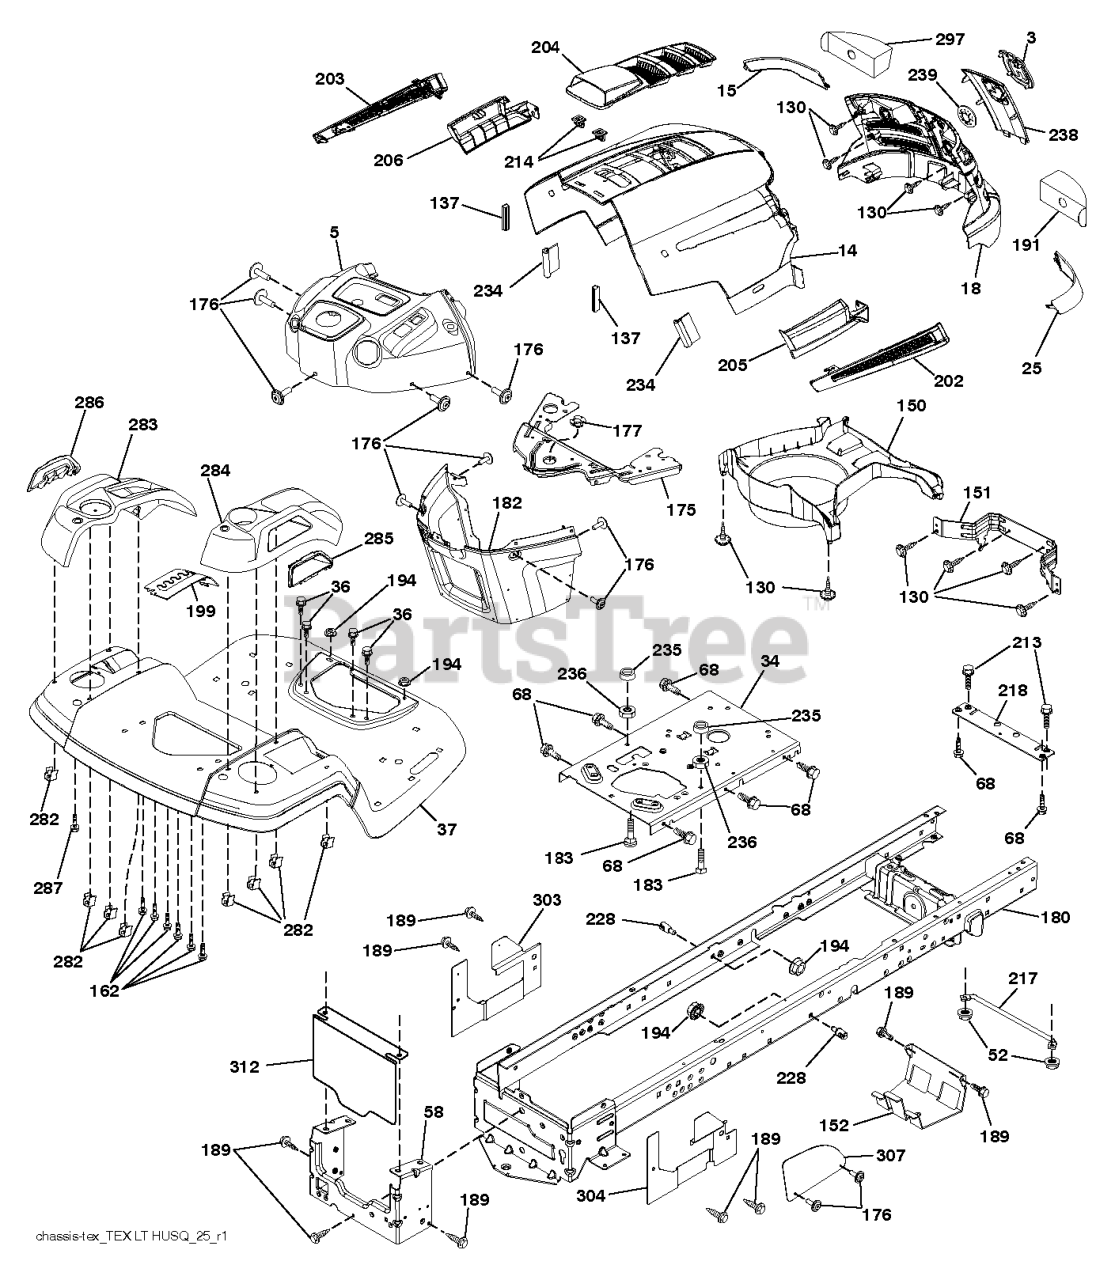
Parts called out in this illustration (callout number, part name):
1	DECK W/DECALS 42"
2	E-RING 1/2 (2 2)
5	BLADE OEM, 14-7/8
6	SPINDLE ASSY - 42/48"
7	SHAFT SEAL
9	SPLINED SHAFT - 42/48"
10	BOTTOM DUST CAP
11	TOP DUST CAP
12	PLUG-VENTED
13	HCS 5/16C X 1 1/4
14	HCS 5/8F X 1 1/4
15	LOCKWASHER 5/8
16	DISCHARGE CHUTE 42"
17	HCS 5/16C X 3/4
19	CARRIAGE BOLT 5/16C X 5/8"
20	CENTER BAFFLE
21	WASHER 5/16 FLAT
22	NUT 5/16 NYLOC
23	MAIN BAFFLE
24	STRUT WLDMT - RT
25	ZERK
26	HCS 5/8C X 2 GR.5
27	STRUT MOUNT WELDMENT
28	HCS 7/16C X 1 1/2
29	LIFT CHAIN
30	NUT 7/16C CENTERLOCK
31	NUT 7/16C WHIZ
32	DRILLED BOLT 7/16-20 X 1 1/2"
33	WASHER 7/16 LOCK
34	SPINDLE WASHER
35	BELT, DECK 42"
36	RP PULLEY - 42/48"
37	IDLER PULLEY (TALL)
38	NUT 3/8-16 NYLOC
39	WASHER 3/8 FLAT
40	IDLER BUSHING
41	IDLER PULLEY
43	4CS 3/8C X 1 SERRATED HEAD
44	NUT 1/2-13 HEX NYLOC ZD
45	WASHER 1/2 FLAT
47	PIVOT BUSHING
48	LT 42 SHIELD
49	WASHER, SUPPORT
50	HCS 1/2C X 3 1/4
51	SCREW 3/8C X 2 3/4 HEX CAP
52	NUT 5/16C CENTERLOCK
53	DECAL, NO STEP
54	DECAL, CPSC
55	DECAL, DANGER
539104621	STRUT SLDMT-LT
539108896	BELT SHIELD - RH
